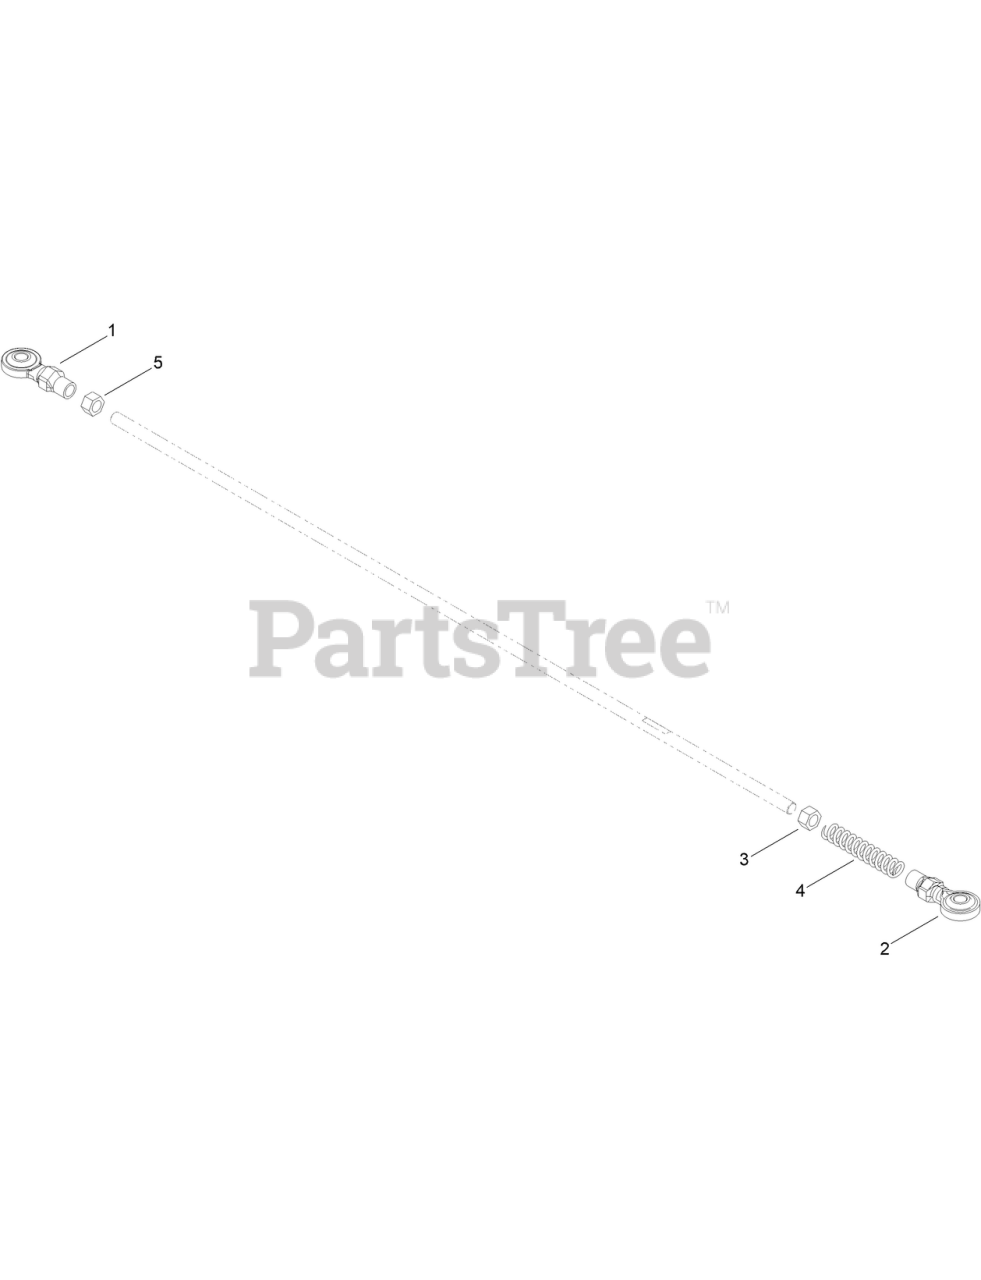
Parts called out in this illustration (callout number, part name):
1	BALL JOINT-LH
2	BALL JOINT-RH
3	NUT-HEX
4	SPRING-RETURN, NEUTRAL
5	NUT-HEX, LH
